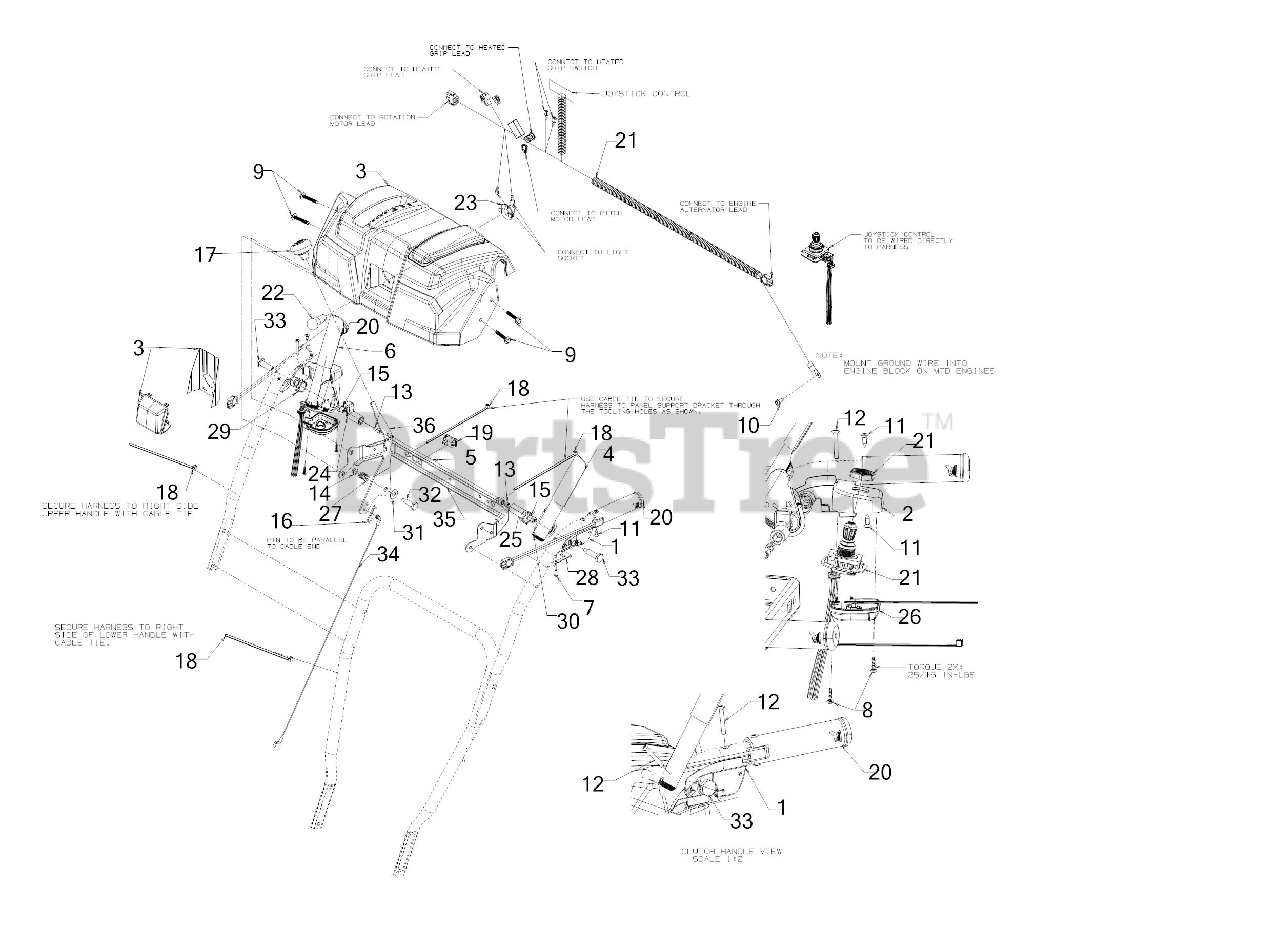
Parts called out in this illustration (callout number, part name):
1	CLUTCH LOCK HANDLE ASSEMBLY (LH)
2	CLUTCH LOCK HANDLE ASSEMBLY (RH)
3	4-WAY HANDLE PANEL ASSEMBLY
4	HANDLE ASSEMBLY (LH)
6	HANDLE ASSEMBLY (RH)
7	SCREW #8-16 x .50
8	SCREW .159 x .610
9	SCREW 1/4-20 x 1.625
10	SCREW 1/4-20 X.500
11	SCREW #10-16 x .625
12	SCREW #10-24 x 1.375
13	SCREW 1/4-20 x .50
14	FLANGE LOCK NUT
15	HEX NUT W/PATCH
16	INTERNAL COTTER PIN
17	SHIFT KNOB
18	7" CABLE TIE
19	HEATED GRIP SWITCH
20	HEATED GRIP HARNESS
23	HEADLIGHT SOCKET
25	CLUTCH LOCK CAM
26	JOYSTICK HOUSING
27	COMPRESSION SPRING
28	CLUTCH SPRING
29	TORSION SPRING
30	RUBBER BUMPER
31	FLAT WASHER
32	SHOULDER SCREW
33	SHOULDER SCREW .437 x 1.345 1/4-20
34	SPEED SELECTOR CABLE (PLASTIC)
